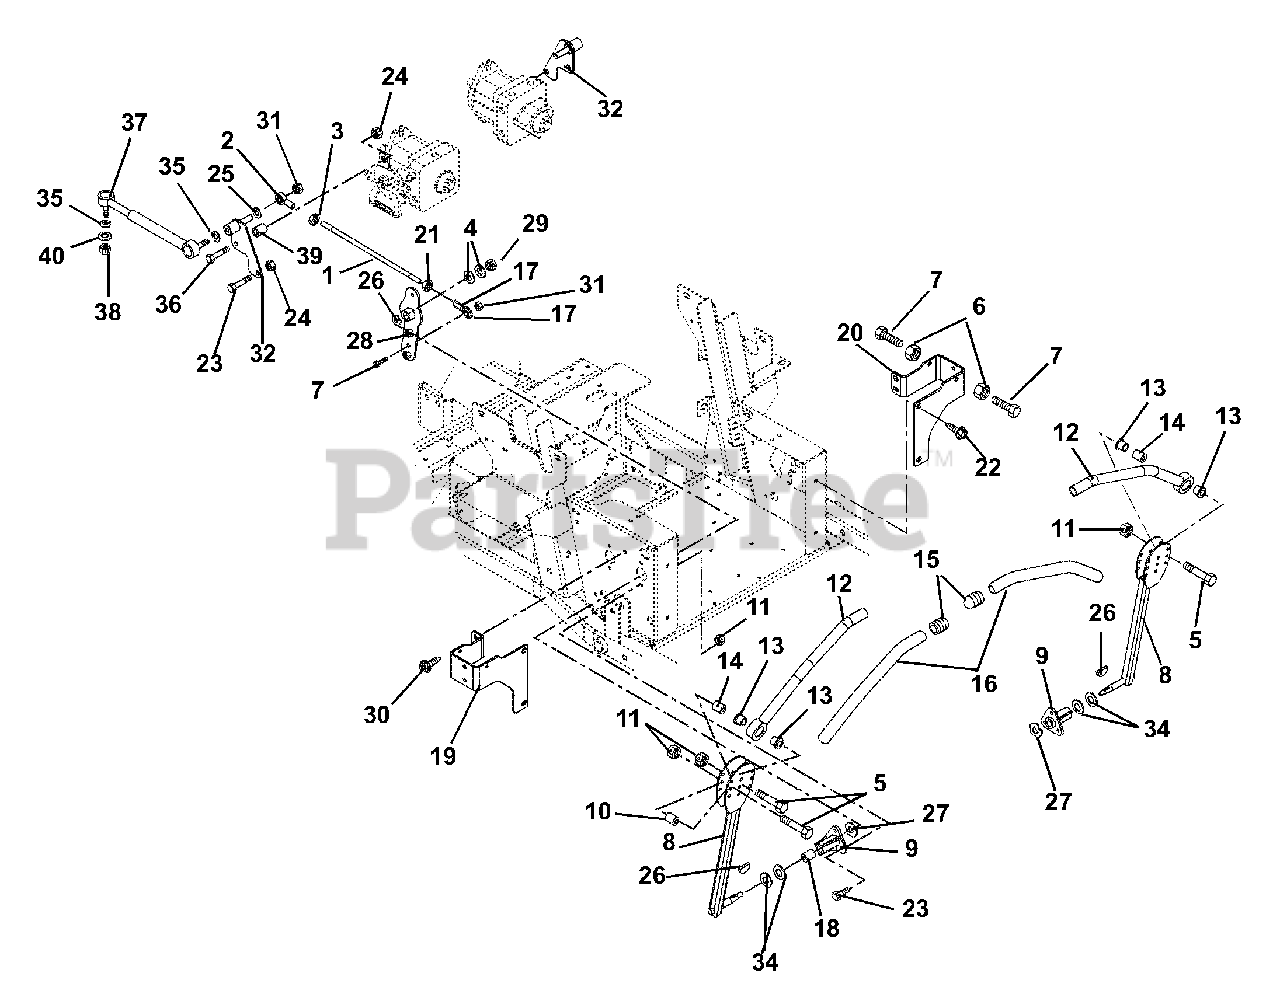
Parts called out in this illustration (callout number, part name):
1	Tie Rod Assembly
2	Rod End, .38 Right Hand
3	Nut, Jam .375-24
4	Washer, Flat Steel .408 x .812 x .065
5	Bolt, Hex .31-18 x 1.75 Grade 5
6	Nut, Hex Jam .375-16
7	Bolt, Hex .375-16 x 1.75
8	Weldment, Control Arm
9	Bushing, Flange
10	Eccentric
11	Nut, Locking Top Flange .31-18
12	Handle Weldment-Left Hand
12	Handle Weldment-Right Hand
13	Bushing, Flange Nylon .762 x 1.48 x .44
15	Caplug, Handlebar
16	Grip, Handlebar
17	Rod End, .38 Left Hand
18	Bushing .625 x .75 x .50
19	Bracket, Stop Right Hand
20	Bracket, Stop Left Hand
21	Nut, Jam .375-24 Left Hand
22	Screw, Tapping .38-16 x .75 Hex Washer Head
23	Bolt, Hex .31-18 x .75 Grade 5
24	Nut, Locking Top Flange .31-18
25	Washer, Locking .38 x .094 Regular
26	Key, Woodruff .13 x .63
27	Washer, Wave
28	Weldment, Pivot Arm
29	Nut, Locking Top Flange .38-16
30	Screw, Tapping .38-16 x .50 Hex Washer Head
31	Nut, Locking Jam Center .375-16
32	Weldment, Return to Neutral/Damper/Rod End
33	Bolt, Hex .38-16 x 1.25 Grade 5
34	Washer, Flat Steel .63 x 1.005 x .062
35	Washer, Locking .31 x .078
36	Bolt-Hex .31-18 x 1.25 Grade 5
37	Damper, Control
38	Nut-Locking-Nylon M8-1.25
39	Spacer .318 x .43 x .375
40	Washer, Flat Steel .38 x .875 x .083
